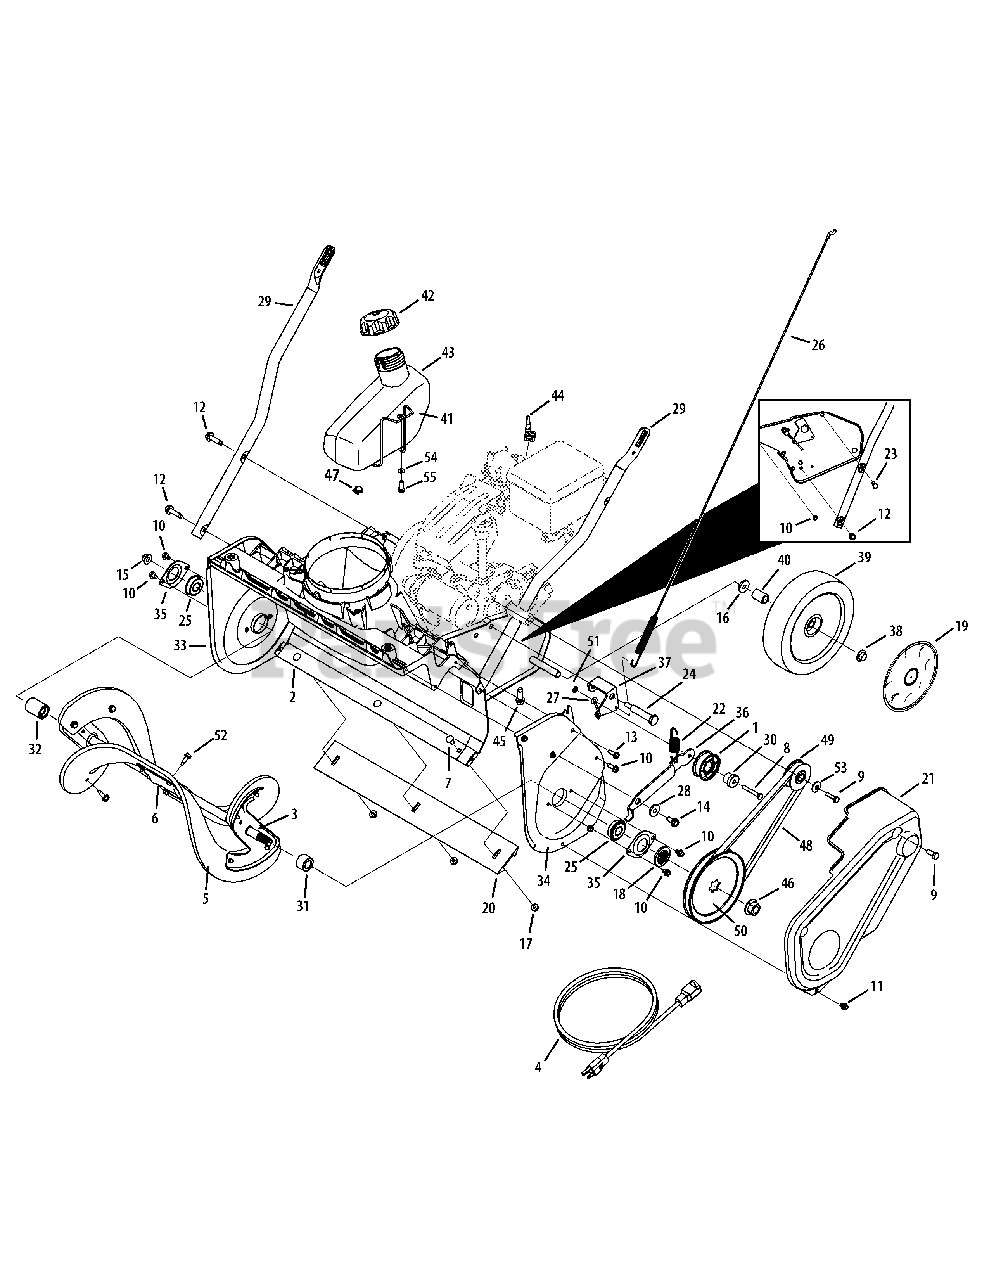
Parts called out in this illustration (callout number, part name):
1	Idler Pulley Assembly
2	Frame
3	Auger Assembly Complete
4	3-Prong Extension Cord
5	Auger Replacement Kit (Inc. 2 Paddles and 12 Hex Washer Screws)
6	Center Auger Bracket
6	Hex Washer Screw 1/4-20 x.750 (4)
7	Carriage Screw, 1/4-20 x .62
8	Hex Screw, 1/4-20 x 1.50
9	Hex Lock Screw, 5/16-24 x .750
10	Hex Washer Screw, 1/4-20 x .625
11	Hex Washer Screw, 1/4-20 x .500
12	Hex Washer Screw, 5/16-18 x 1.250
13	Hex Washer Screw, 1/4-15 x .750
14	Hex Washer Screw, 5/16-18 x .75
15	Flange Lock Nut, 3/8-16
16	Flat Washer, .535 x .930 x .090
17	Flange Lock Nut, 1/4-20
18	Pulley Hub
19	Hubcap
20	Shave Plate
22	Extension Spring, .70 x 3.035
23	Hex Screw, 5/16-24 x 1.25
24	Shoulder Bolt, 5/16-24 x .496 x 2.18
25	Ball Bearing, .500 x 40mm x 12mm
26	Clutch Cable
27	Drive Cable Wire Support
28	Shoulder Spacer
30	Shoulder Spacer, .260 x .785 x .538
31	LH Auger Spacer
32	RH Auger Spacer
33	RH Auger Plate
34	LH Auger Plate
36	Idler Bracket
37	Cable Idler Bracket
38	Push Cap, 1/2
39	Wheel, 8 x 2 (Gray)
39	Wheel, 7 x 2 (Black)
40	Sleeve Spacer, .525 x .78 x 1.00
40	Spacer, .525 x .775 x .835
41	Gas Tank Wire Support
42	Fuel Cap
43	Fuel Tank
44	Choke Extension Lever
45	Hex Washer Screw, 3/8-16 x 1.000
46	Flange Nut, 7/16-20
47	Hose Clamp
48	Belt, .500 x 35.06
49	Pulley Half, .625 x 2.25
50	Pulley, 1/2 x 6.00
52	Hex Washer Screw, 1/4-20 x .750
53	Thrust Washer, .330 x 1.25 x .120
54	Washer, .265 x 1.00 x .030
55	Screw, 1/4-10 x .625
